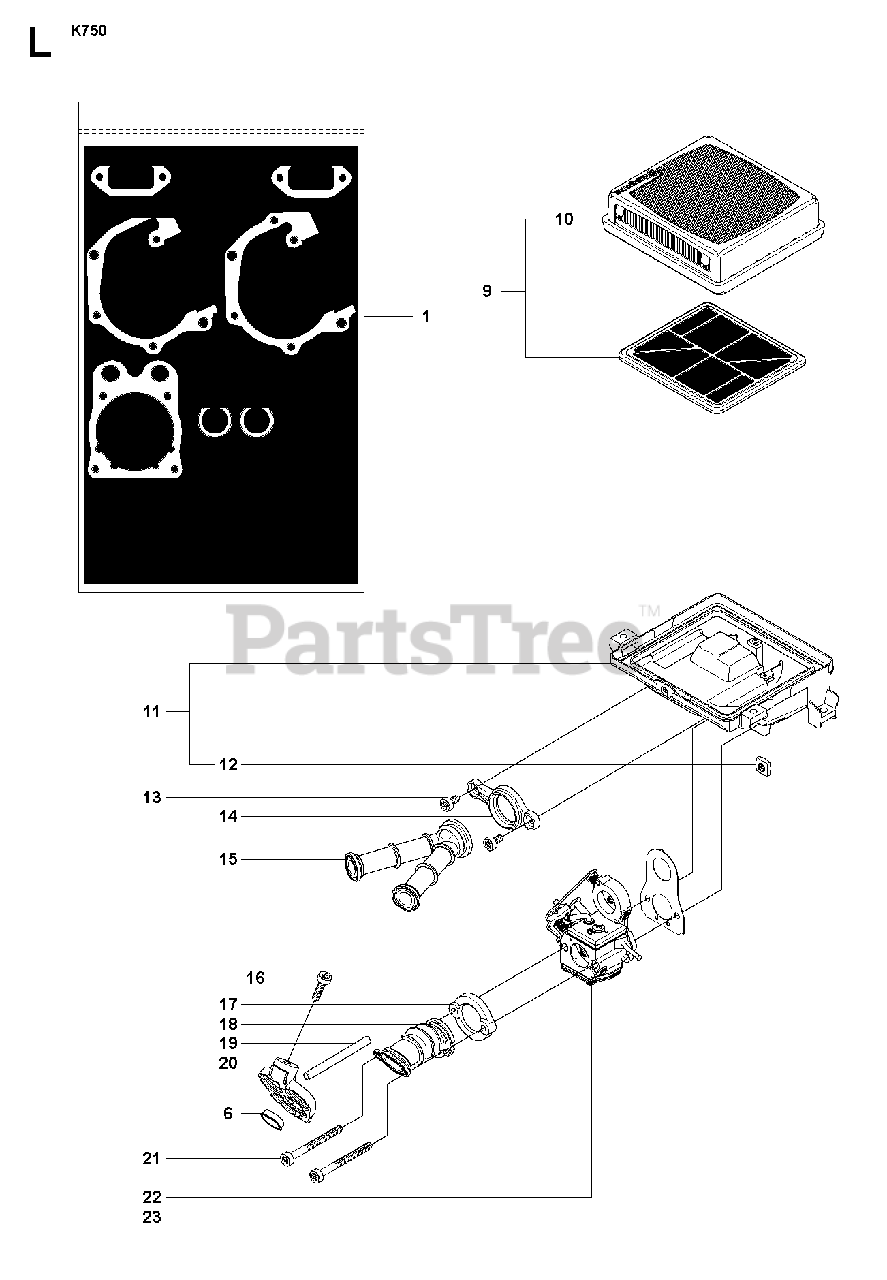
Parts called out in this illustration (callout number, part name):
1	GASKET KITIncl. 2 - 8, 23
3	GASKET
7	SEALING RING
9	FILTERIncl. 10
10	AIR FILTER
11	CARBURETTOR BRACKETIncl. 12
13	SCREW ITXSCM
14	FLANGE INLET PIPE
15	INLET PIPE
16	SCREW ITXSCM
17	FLANGE INLET PIPE
18	INLET PIPE
19	IMPULSE HOSE
21	SCREW ITXSCM
22	CARBURETTORZama C3-EL29
22	CARBURETTORJapan only
23	GASKET
